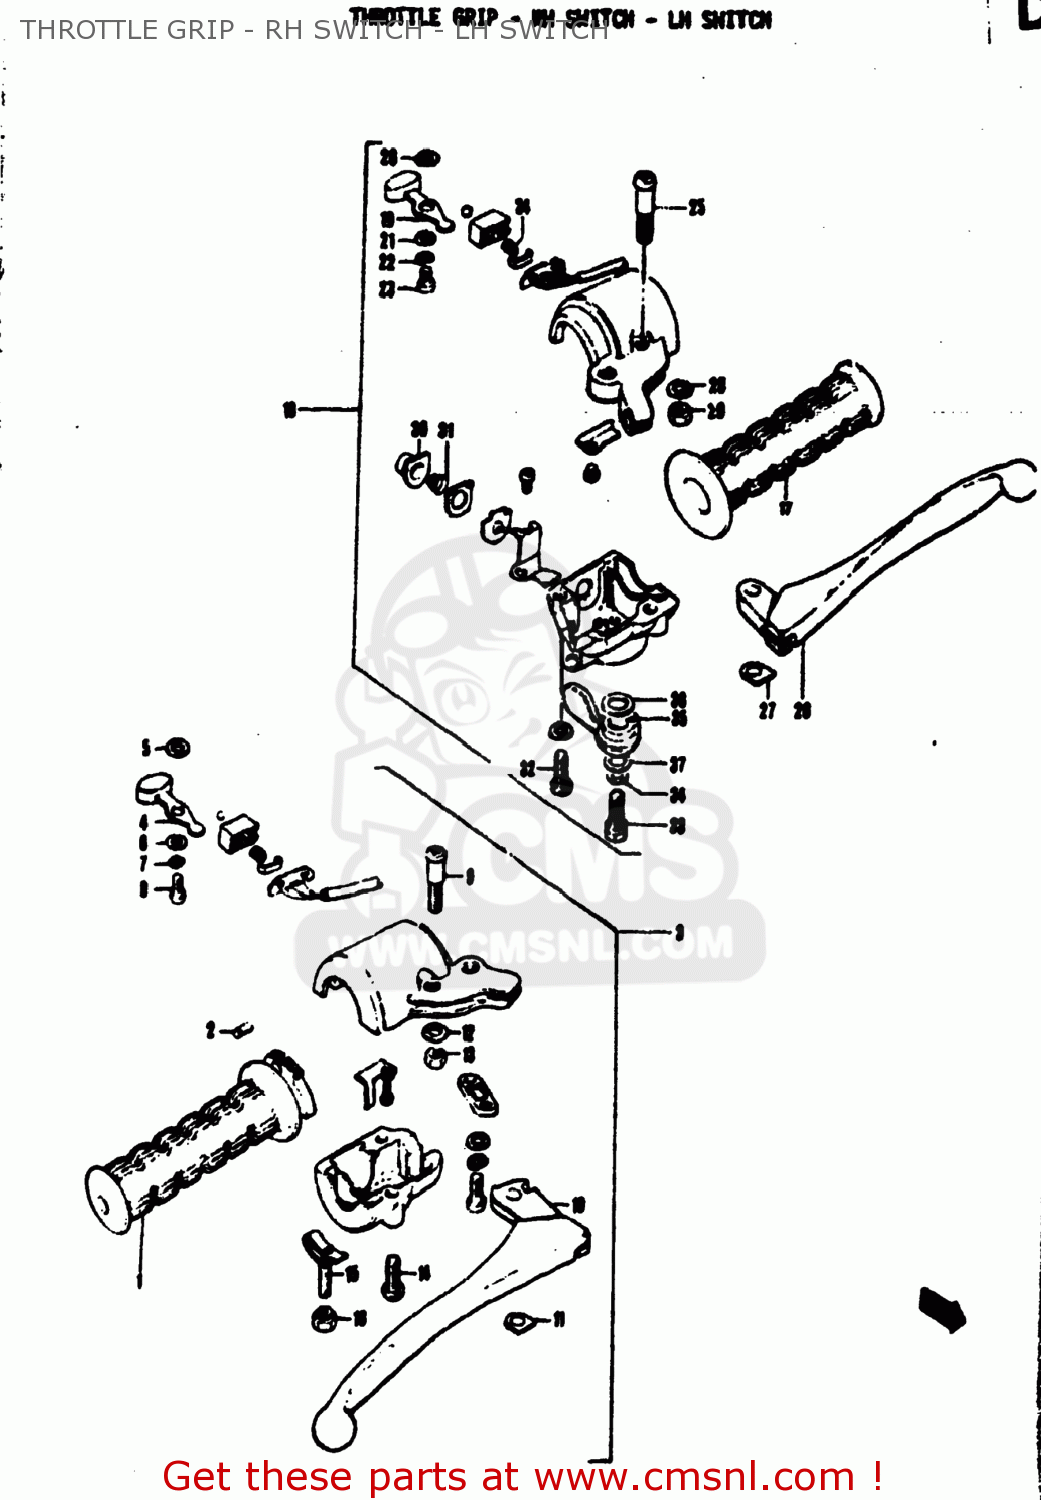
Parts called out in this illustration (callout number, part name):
1	GRIP,THROTTLE
2	PIECE,THROTTLE END
3	LEVER/SWITCH AS
4	KNOB,DIMMER SWITCH
5	WASHER,DIM SWITCH KNOB
6	WASHER
7	LOCK WASHER
8	SCREW
9	BOLT,LEVER
10	LEVER,BRAKE
11	SPACER,LEVER
12	LOCK WASHER
13	NUT
14	SCREW
15	ADJUSTER,GRIP
16	NUT
17	GRIP
18	LEVER ASSEMBLY
19	KNOB,DIMMER SWITCH
20	WASHER,DIM SWITCH KNOB
21	WASHER
22	LOCK WASHER
23	SCREW
24	SPRING,TURN SIGNAL SWITCH CONTACT
25	BOLT,LEVER
26	LEVER,CLUTCH
27	SPACER,LEVER
28	LOCK WASHER
29	NUT
30	BUTTON
31	SPRING
32	SCREW
33	BOLT
34	LOCK WASHER
35	LEVER,STARTER
36	WASHER,ADJUSTER
37	WASHER,STARTER LEVER
